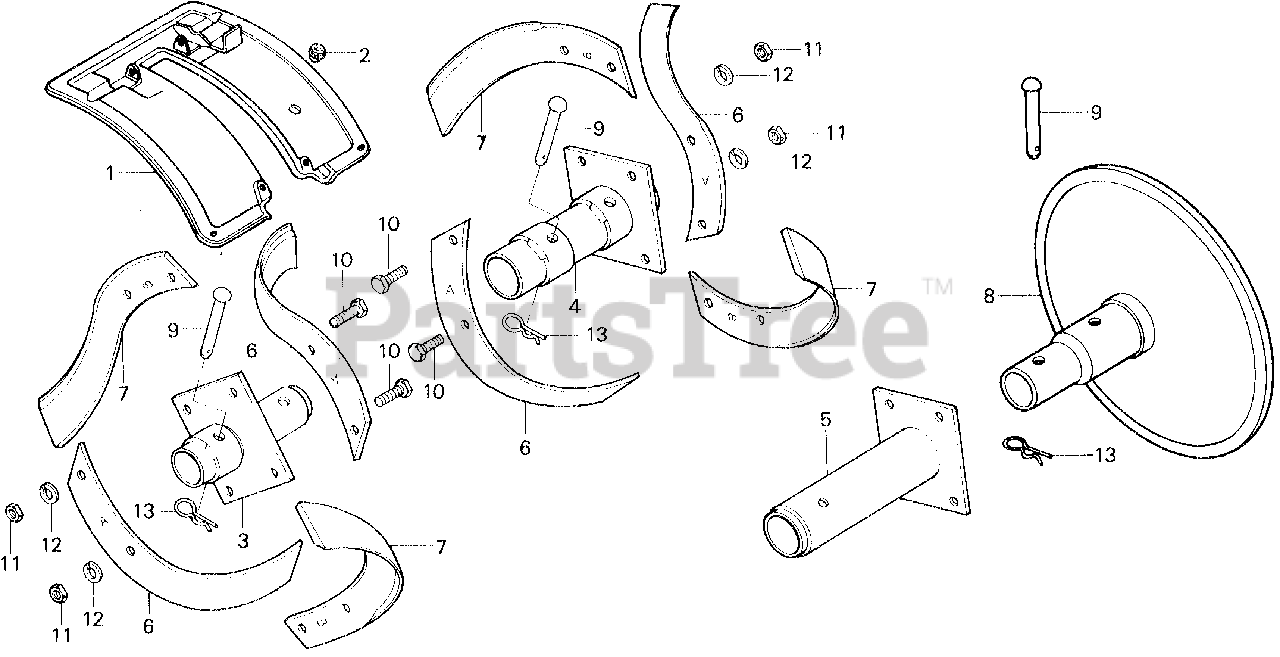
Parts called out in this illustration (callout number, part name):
1	FENDER, MAIN *NH31* (MCKINLEY WHITE)
2	STOPPER, TENSIONER ARM
3	PIPE (INNER)
4	PIPE (OUTER) (NOT AVAILABLE)
5	PIPE, EXTENSION
6	TINE A, ROTARY
7	TINE B, ROTARY
8	DISK, SIDE Use up to Frame SN 2149605.
9	PIN (10X53.5)
10	BOLT, HEX. (10X25)
11	NUT, HEX. (10MM)
12	WASHER, SPRING (8MM)
13	PIN, LOCK (10MM)
13	PIN, LOCK (10MM) Use from Frame SN 2149606 to 2149605.
